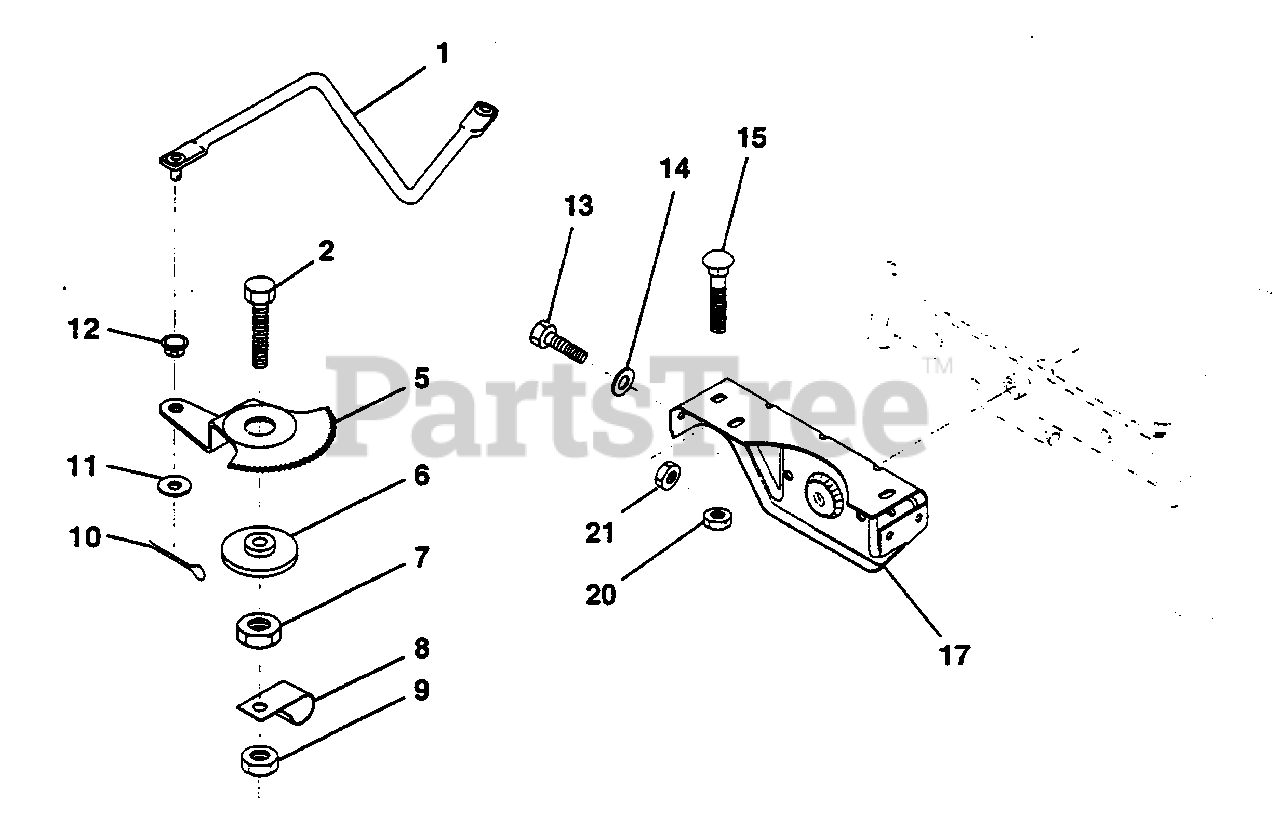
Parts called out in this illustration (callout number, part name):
1	Link, Drag (AYP part number)
2	Bolt, Hex Head, Fin. 1/2-13 x 1-3/4 (AYP part number)
5	Gear, Sector (AYP part number)
6	Bushing (AYP part number)
7	Nut, Hex, Heavy, Top Lock 1/2-13 UNC (AYP part number)
8	Clip, Insulated (AYP part number)
9	Nut, Crownlock 3/8-16 (AYP part number)
10	Pin, Cotter 1/8 x 3/4 (AYP part number)
11	Washer 13/32 x 13/16 x 16 Gauge (AYP part number)
12	Bushing (AYP part number)
13	Bolt, Hex Head 5/16-18 UNC x 3/4 (AYP part number)
14	Washer 11/32 x 7/8 x 16 Gauge (AYP part number)
15	Bolt, Carriage 3/8-16 UNC x 3/4 (AYP part number)
17	Support, Front Axle (AYP part number)
20	Nut, Crownlock 3/8-16 UNC
21	Nut, Crownlock 5/16-18
